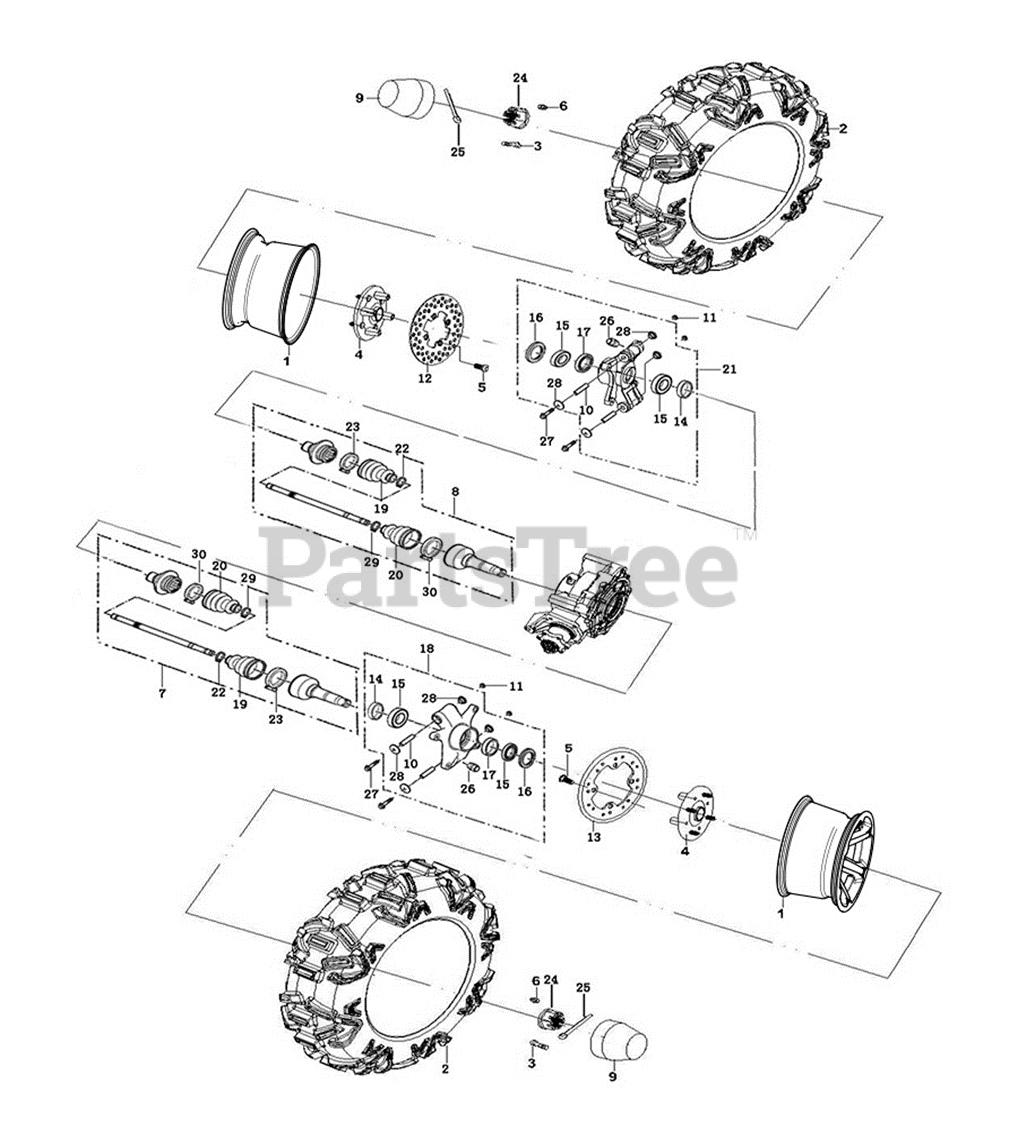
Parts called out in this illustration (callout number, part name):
1	RIM - REAR
1	REAR RIM - BLACK
2	TIRE RADIAL - REAR
3	VALVE-CYCLE
5	BOLT M8X15-15X5
6	TAPER NUT M10X1.25
7	REAR LEFT CONSTANT VELOCITY JOINT
8	REAR RIGHT CONSTANT VELOCITY JOINT
9	DUST COVER HUB
10	STEERING KNUCKLE TUBE (REAR)
11	LOCK NUT M10X1.25
12	DISC BRAKE - REAR RIGHT
13	DISC BRAKE - REAR LEFT
14	REAR KNUCKLE INSIDE OIL SEAL
15	BEARING 6206RS
16	REAR KNUCKLE OUTSIDE OIL SEAL
17	REAR STEERING KNUCKLE TUBE
18	STEERING KNUCKLE (REAR LH)
19	RUBBER BOOT
20	AXLE RUBBER BOOT
21	STEERING KNUCKLE (REAR RH)
22	CLAMP - LARGE
23	CLAMP - LARGE
24	SLOTTED NUT M24X1.5
25	COTTER PIN 3.2X50
26	KNUCKLE OIL FITTING
27	HEX HEAD FLANGE BOLT M12X1.25-110
29	CLAMP - LARGE
30	CLAMP - LARGE
